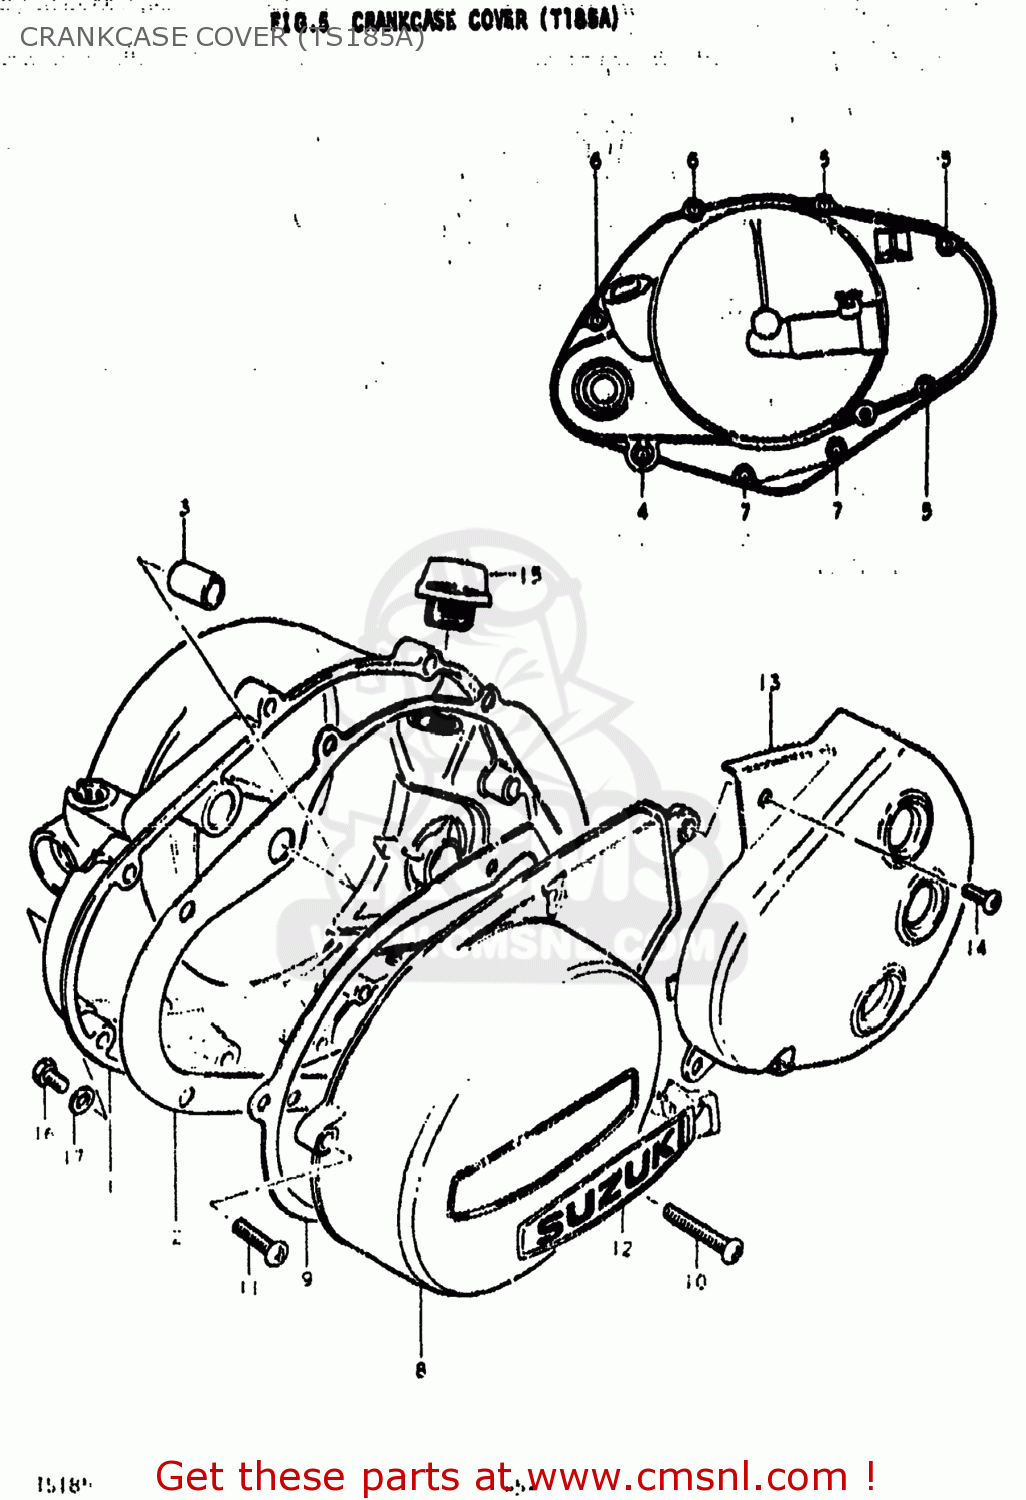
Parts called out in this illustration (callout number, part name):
1	COVER,CLUTCH
2	GASKET,CLUTCH COVER (AS (MCA)
3	PIN
4	SCREW
5	SCREW (6X35)
6	SCREW
7	SCREW
8	COVER
9	GASKET,MAGNETO COVER (MCA)
10	SCREW
11	SCREW
12	EMBLEM,MAGNETO COVER
13	COVER,SPROCKET
14	SCREW
15	PLUG
16	SCREW(6X10)
17	GASKET(6.2X11X1) (NAS)
